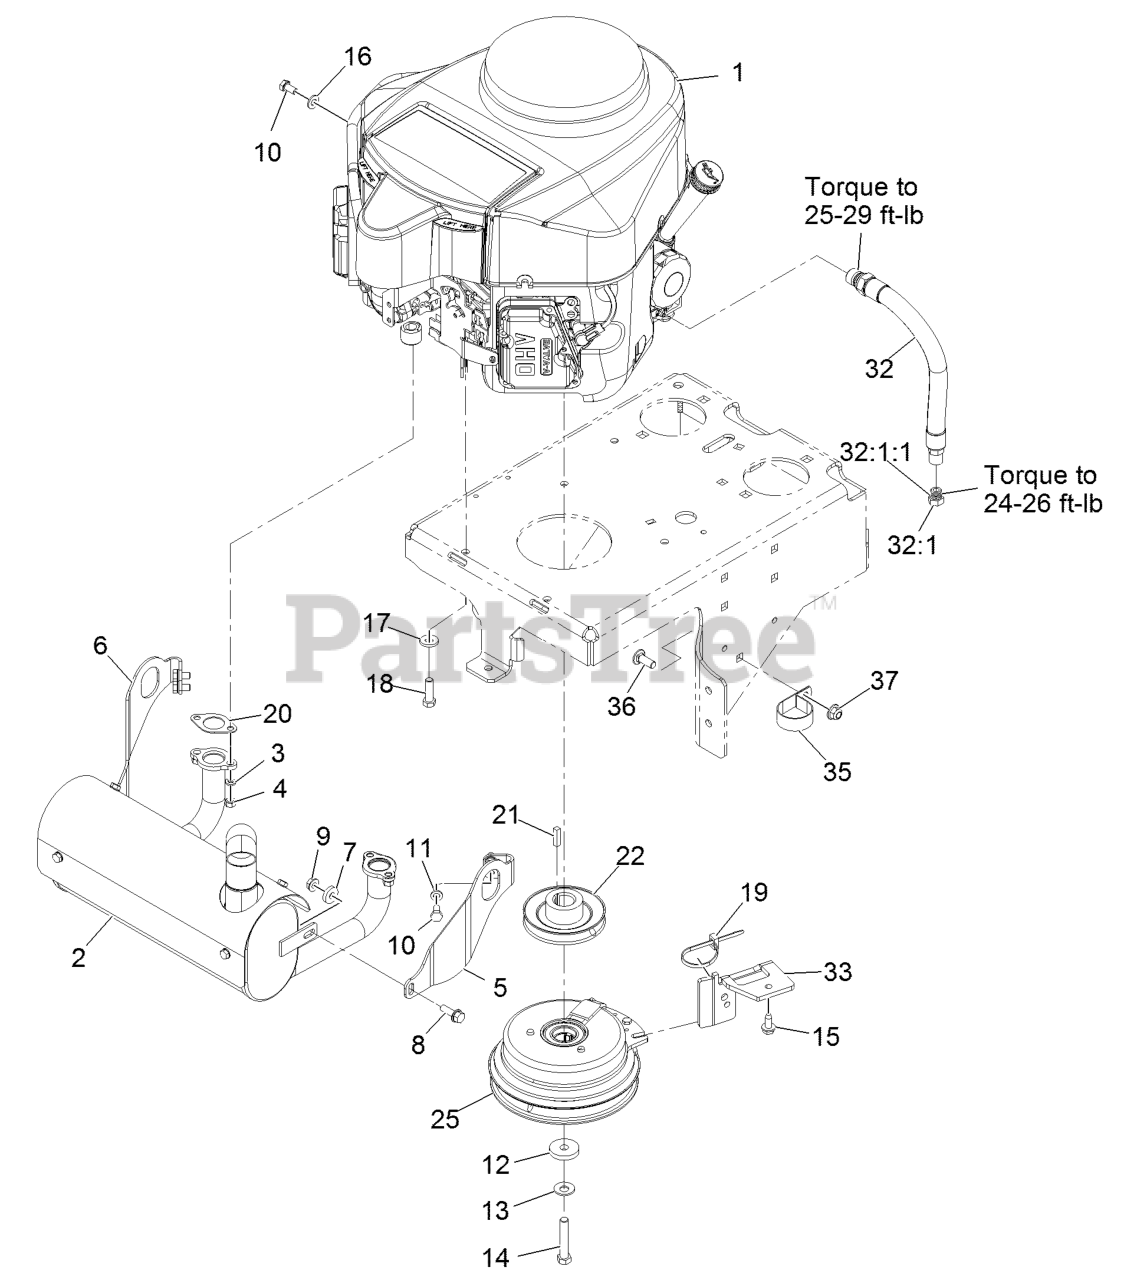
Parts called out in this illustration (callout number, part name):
1	Engine-Kawasaki
3	WASHER-LOCK
5	BRACKET-MUFFLER MOUNT, LH
6	BRACKET-MUFFLER MOUNT, RH
8	SCREW-HHF
10	SCREW-HH
11	WASHER-LOCK
12	WASHER
13	WASHER-SPRING
14	SCREW-HH
15	Screw-HWH 5/16-18 X 3/4 Tf
16	WASHER-PLAIN
17	WASHER-BELLEVILLE
18	SCREW-HH
19	TIE-CABLE
20	GASKET-EXHAUST
25	CLUTCH-WARNER
32	ENGINE OIL DRAIN HOSE ASM
32:1	PLUG-HH
32:1:1	O-RING
33	BRACKET-ANCHOR, CLUTCH
35	CLAMP-R
36	SCREW-CARR
37	NUT-HF, NI
